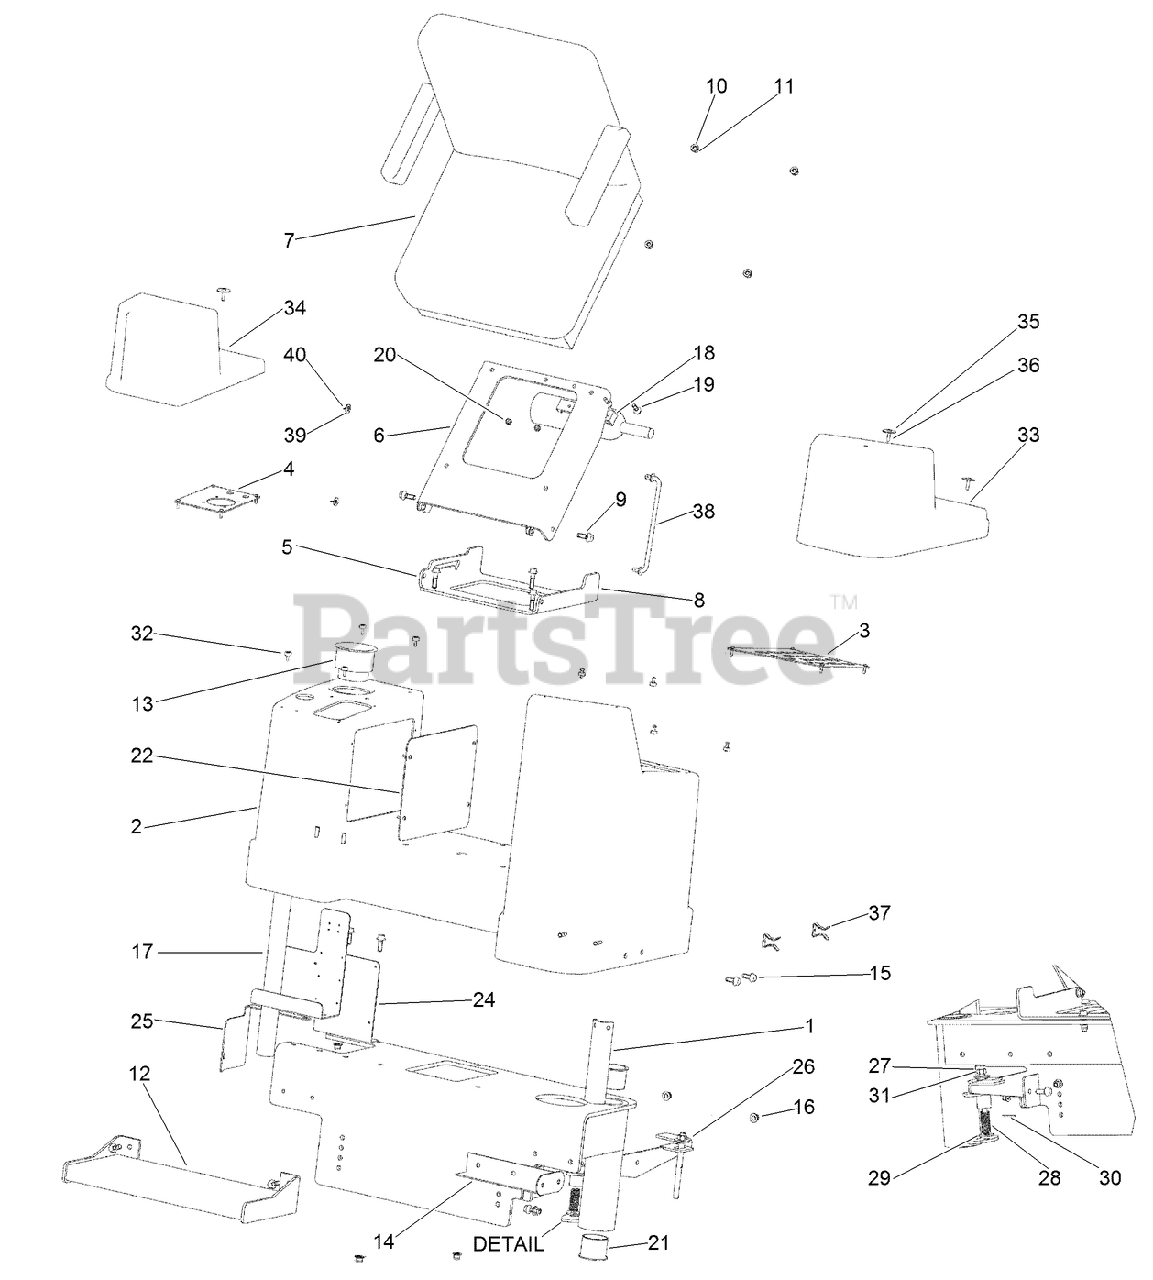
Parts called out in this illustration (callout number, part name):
1	WELDMENT - Operators Console
2	CONSOLE - Fiberglass
3	PLATE - Cover, Left Console
4	PLATE - Mounting
5	PLATE - Seat Mount Bottom
6	PLATE - Seat Mount Top
7	OPERATOR SEAT ASM (STATIC)
8	SCREW-HHF
9	SCREW-HH
10	WASHER - 0.406 x 0.750 x 0.119 in CST ZND
11	NUT - Hex .375 - 16 GR8 PHC
12	ASSEMBLY - Foot Rest
13	CUP-HOLDER
14	WELDMENT - Operators Console Support
15	SCREW-FLANGE
16	NUT-FLANGE, NYLOCK
17	WELDMENT - Umbrella Mount
18	EXTINGUISHER - Fire
19	SCREW-HH
20	NUT, METRIC FLANGE PREVAILING - M6 Zinc
21	BEARING-FLANGED
22	PLATE - Seat Ins Panel
24	PLATE - CPU Mount
25	PLATE - Mount
26	ARM - Seat Adjustment
27	ROD-SWING, SEAT
28	SPRING-PIVOT LOCK, SEAT
29	WASHER-FLAT
30	PIN-COTTER
31	NUT-Hex 0.500-13 GR5 ZND
32	GROMMET-RUBBER
33	COVER-PROTECTIVE, LEFT
34	COVER-PROTECTIVE, RIGHT
36	SCREW - Button Head (Allen)
37	CLIP - Ground Stake
38	ROD-PROP, SEAT
39	WASHER-0.406 x 0.812 x 0.065 in CST ZND
40	PIN - Cotter .094 x .75 in ZN
